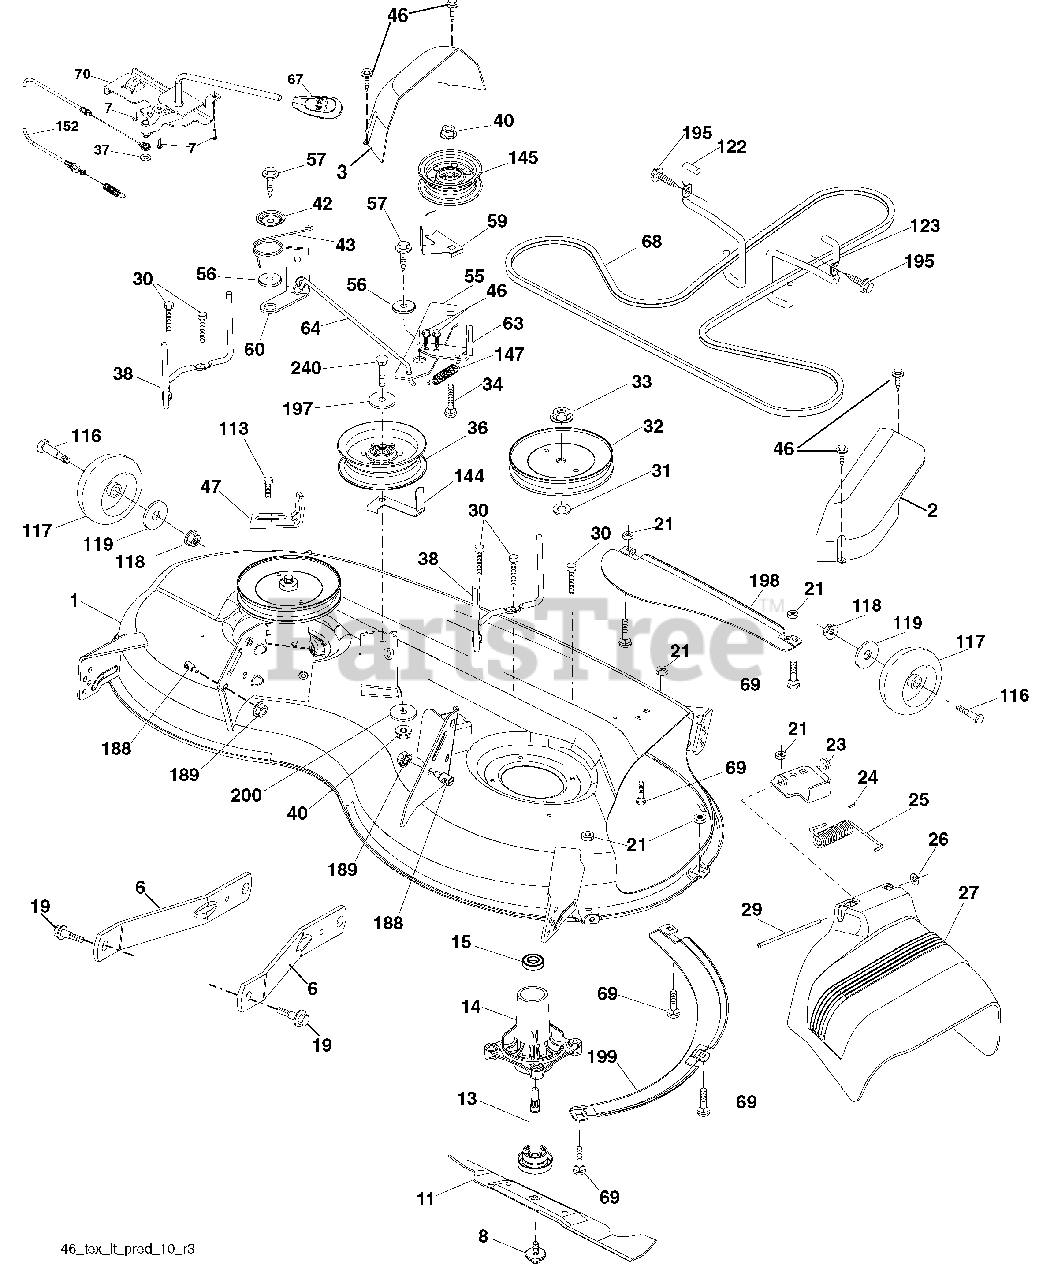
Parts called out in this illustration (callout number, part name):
2	Cover Mandrel RH
3	Cover Mandrel LH
5	Retainer Spring
6	Arm Suspension
7	Screw 10 x.750 BOS Thread
8	Bolt/Washer Asm 7/16-20 unf
11	Blade Mower
13	Shaft Assembly, Mandrel
14	Housing, Mandrel
15	Bearing, Ball, Mandrel
19	Bolt, Shoulder
21	Nut
23	Bracket, Deflector
24	Cap, Sleeve
25	Spring, Torsion, Deflector
26	Nut, Push
27	Shield, Deflector
29	Rod, Hinge
30	Screw Thdrol Rolling Wsh Hd
31	Washer, Spacer
32	Pulley, Mandrel
33	Nut, Toplock, Flanged
34	Bolt Carr Sh. 3/8-16 x 1-1/2 Gr. 5
36	Pulley, Idler
37	Washer 13/32 x 13/16 x 16 Ga.
38	Keeper Belt LH Mandrel
40	Nut, Lock Flg. 3/8-16 unc
42	Spring Torsion Brake
43	Spring Torsion Retainer
46	Screw
47	Bracket Clutch Cable
55	Arm, Idler
56	Spacer, Retainer
57	Screw Hexwsh Thd 3/8-16 x 1
59	Guard, Tuv Idler (94)
60	Arm Brake Mower
63	Arm Brake Mower
64	Linkage Brake
67	Handle, Clutch Cable
68	V-Belt
69	Bolt
70	Clutch Asm. Manual
113	Screw 5/16-18
116	Bolt, Shoulder
117	Wheel, Gauge
118	Nut, Crownlock 3/8-1
119	Washer 13/32 x 7/8 x 14 Ga.
122	Keeper Belt Eng. LH
123	Keeper Belt Eng. RH
144	Keeper Belt
145	Pulley Idler
147	Spring Return
152	Cable Clutch Manual w/Spr.
188	Stud Fastener
189	Nut Lock Hex Flange
195	Screw 3/8-16 x 3/4
197	Washer 13/32 x 13/16 x 12 Ga.
198	Baffle Center Front
199	Baffle Front RH
200	Washer 13/32 x 1 x 1/2 11 Ga.
240	Bolt Fin Hex 3/8-16 x 2-1/4 Gr. 5
240	Mandrel Assembly
240	Replacement Mower, Complete
